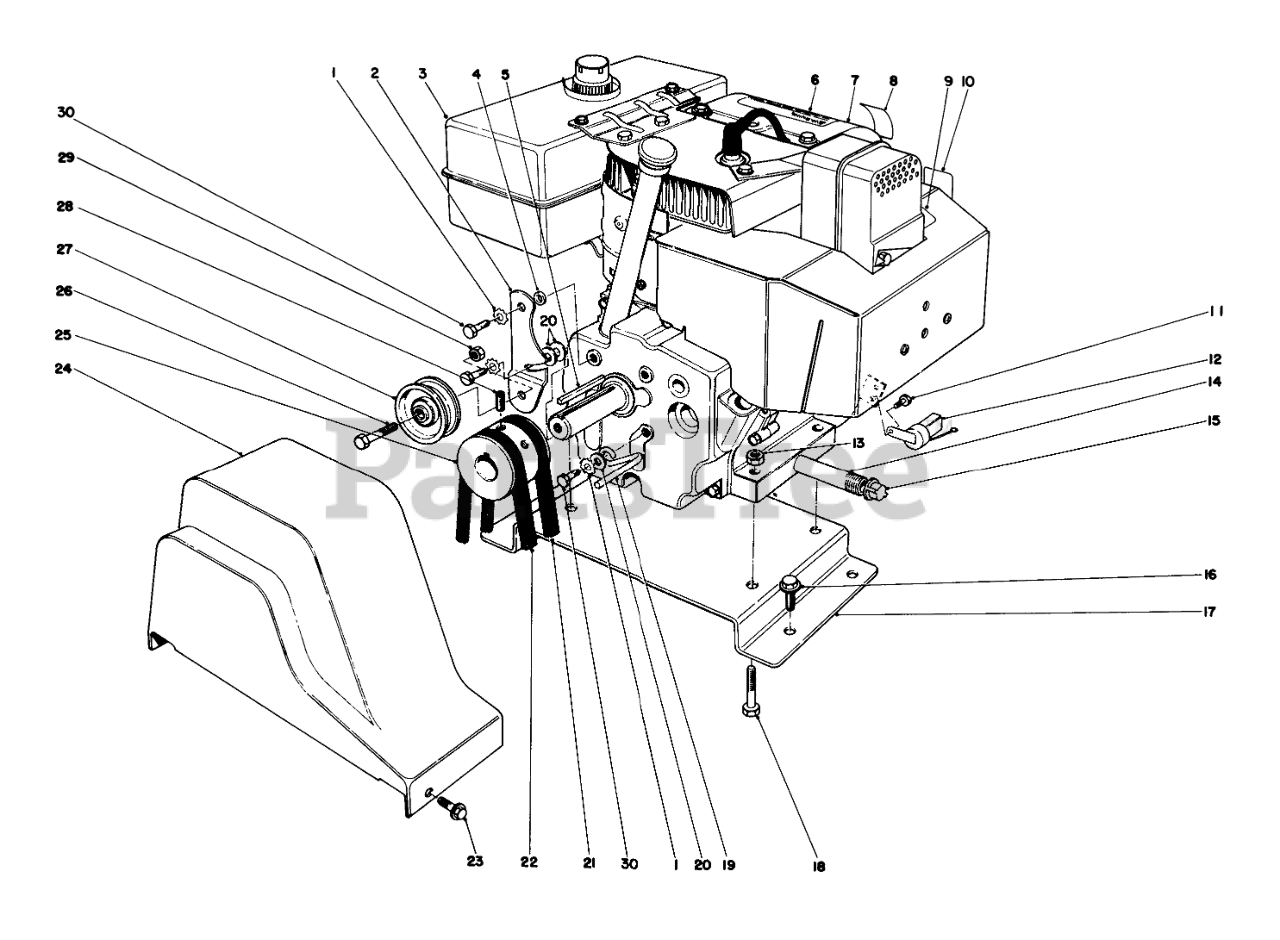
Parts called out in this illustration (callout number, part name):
1	WASHER-LOCK
2	ENGINE IDLER ARM
3	Fuel Tank w/Cap
4	SPACER
6	CAUTION DECAL
7	Engine
8	PRIMER DECAL
9	HOT SURFACE DECAL
10	CHOKE DECAL
11	SCREW-HWH
12	INTERLOCK MODULE
13	NUT-LOCK, NI
14	NIPPLE-PIPE
15	CAP-PIPE
16	SCREW-HWHTF
17	Plate ngine Mounting
18	SCREW-HH
19	BELT RETAINER
20	WASHER-PLAIN
21	V-BELT
22	V-BELT
23	SCREW-HWH
24	BELT GUARD
25	ENGINE PULLEY
26	SCREW-HH
27	PULLEY-IDLER
28	SETSCREW
29	NUT-LOCK, NI
30	SCREW-HH
